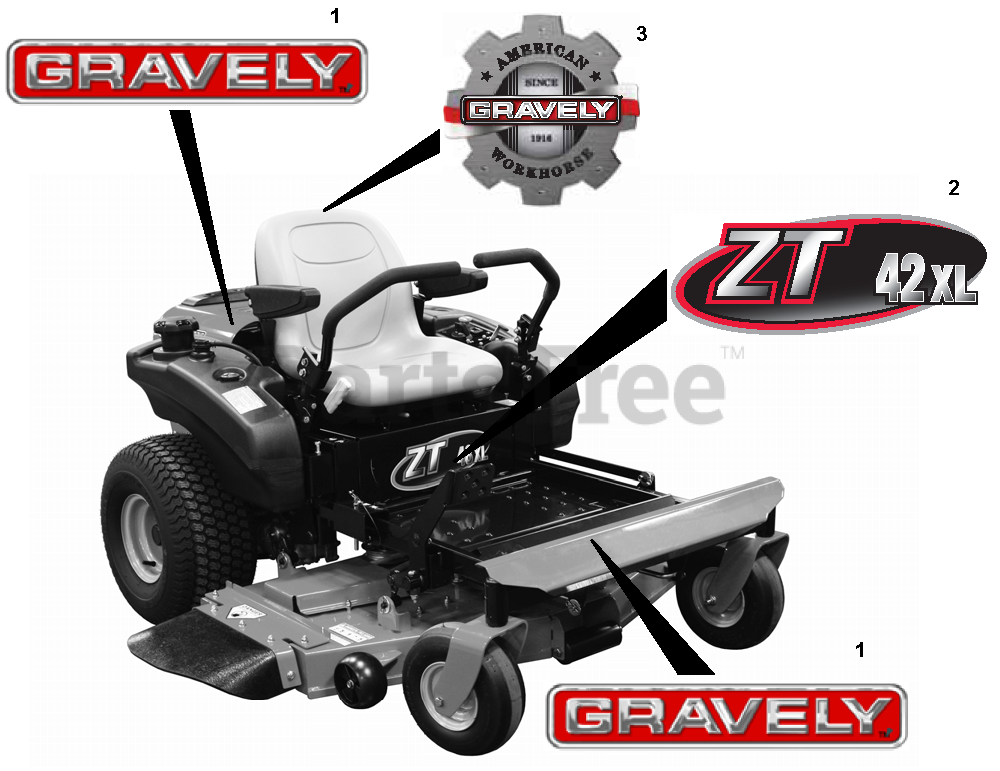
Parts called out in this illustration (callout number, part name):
1	DECAL, 9.5" GRAVELY LOGO
2	DECAL, ZT 42 XL
2	DECAL, ZT 48 XL
2	DECAL, ZT 54 XL
3	DECAL, GRAVELY HERITAGE-LARGE
